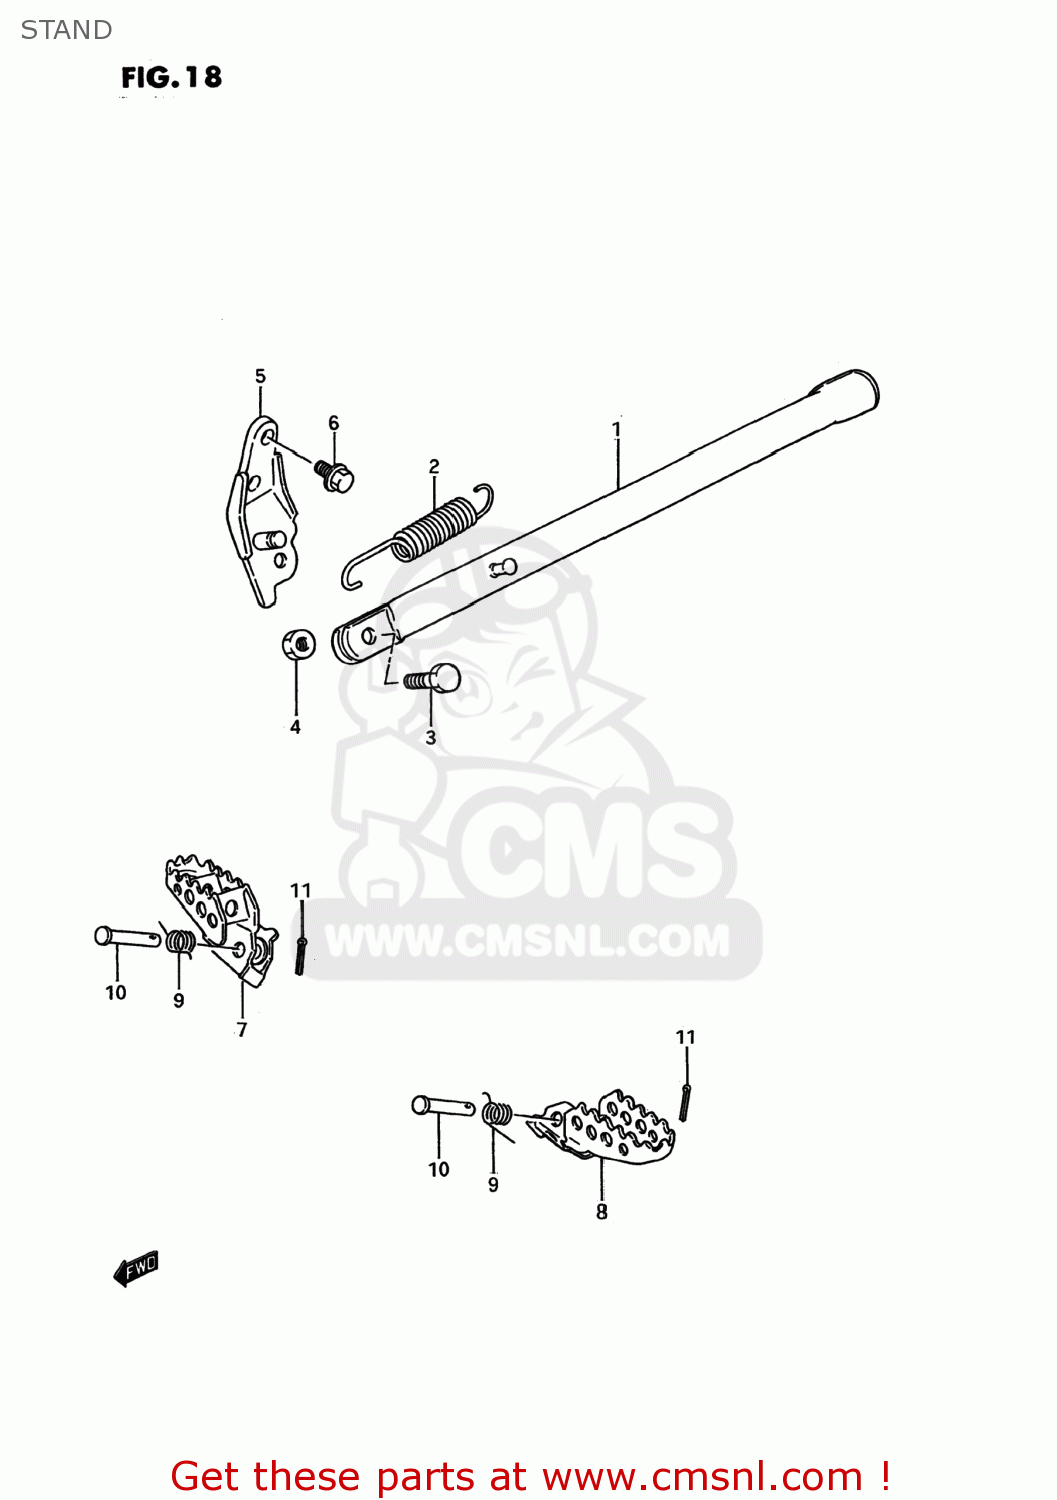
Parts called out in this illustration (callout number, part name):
1	STAND,SIDE
2	SPRING
3	BOLT(8X25)
4	NUT
5	BRACKET,SIDE STAND
6	BOLT
7	FOOTREST COMP,FRONT,RIGHT
8	FOOTREST COMP,FRONT,LEFT
9	SPRING
10	PIN
11	PIN
